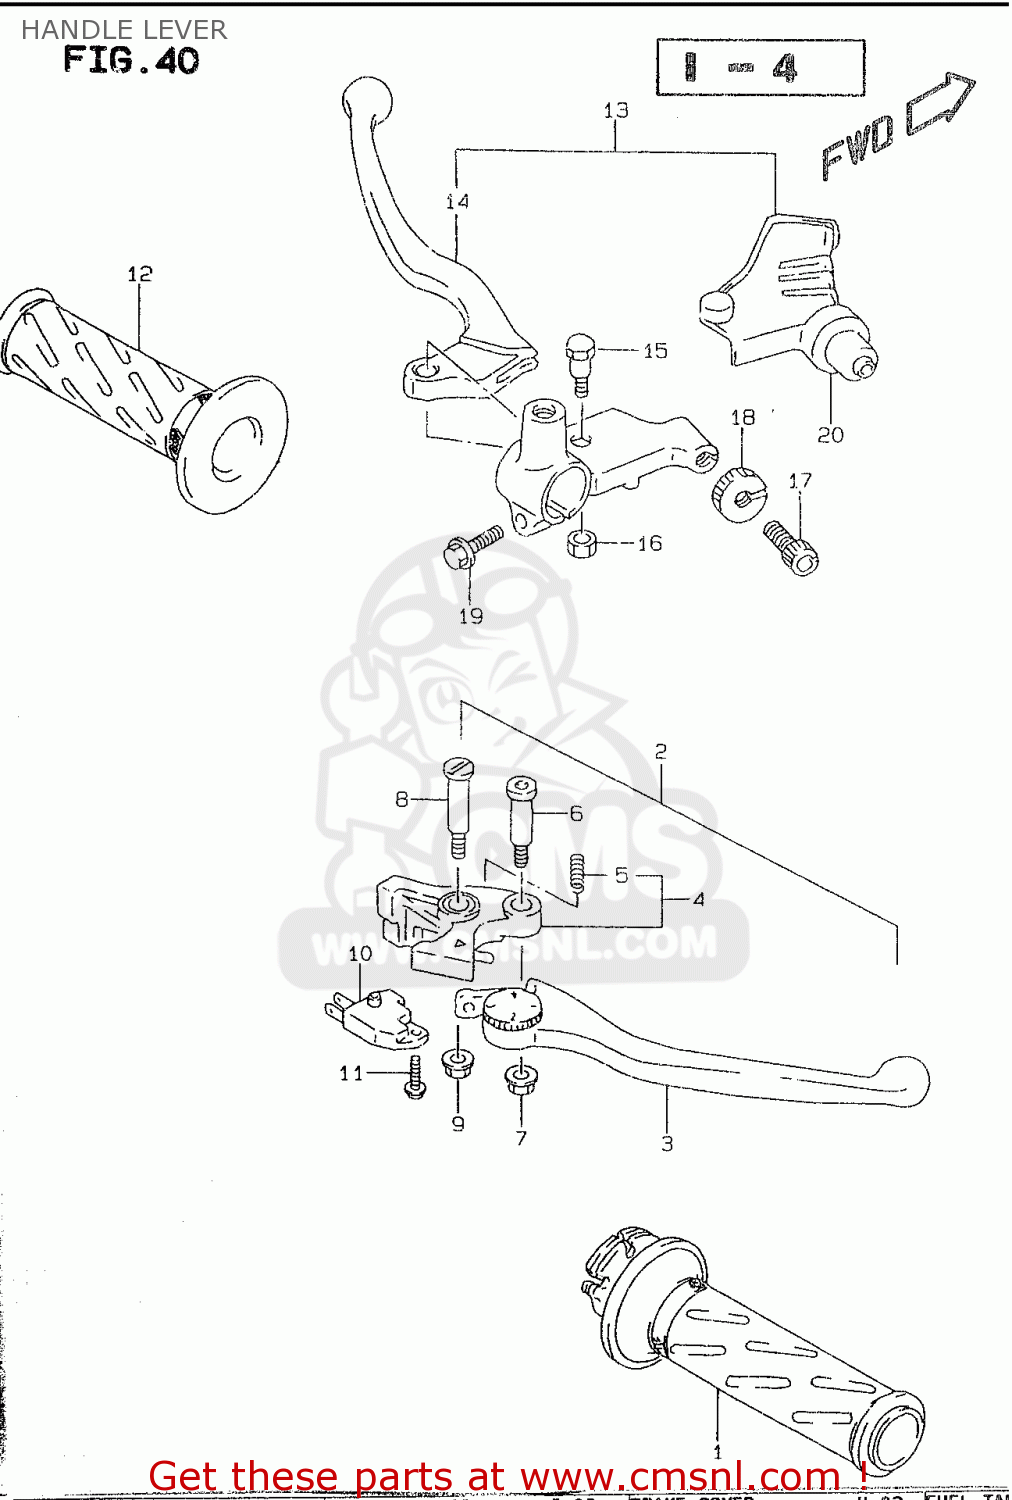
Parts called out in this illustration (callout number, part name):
1	GRIP,THROTTLE
2	LEVER ASSY,BRAKE
3	LEVER,ADJUST
4	KNOCKER
5	SPRING
6	BOLT,LEVER
7	NUT
8	BOLT,LEVER PIVOT
9	NUT
10	SWITCH ASSEMBLY,STOP
11	SCREW
12	GRIP,LEFT
13	LEVER ASSY,CLUTCH
14	LEVER,CLUTCH
15	BOLT,LEVER SET
16	NUT
17	ADJUSTER,CABLE
18	NUT,CABLE ADJUSTER
19	SCREW
20	COVER,CLUTCH LEVER
